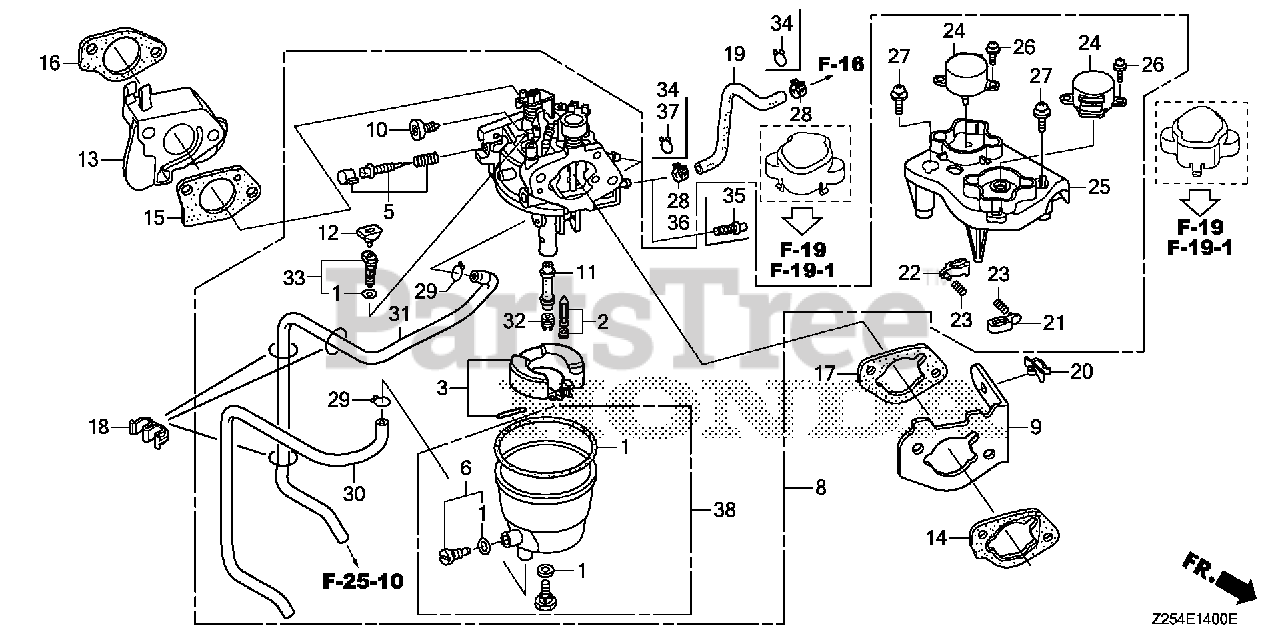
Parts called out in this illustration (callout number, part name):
1	GASKET SET (CARBURETOR NO.)
2	VALVE SET, FLOAT
4	CHAMBER SET, FLOAT
5	SCREW SET, PILOT
6	SCREW SET, DRAIN
7	SCREW SET
8	CARBURETOR ASSY. (BE89G A)
9	HOLDER, TUBE
10	SCREW, STOP
11	NOZZLE, MAIN
12	COLLAR, SETTING
13	INSULATOR, CARBURETOR
14	SPACER, CARBURETOR
15	GASKET, CARBURETOR
16	GASKET, INSULATOR
17	GASKET, AIR CLEANER
18	CLAMP, TUBE (7.5X2)
19	TUBE, FUEL TANK (FKM)
20	CLIP B, HARNESS
21	LEVER, LINK
22	LEVER, LINK
23	SPRING, COMPRESSION COIL
24	MOTOR, THROTTLE CONTROL
25	BRACKET, THROTTLE MOTOR
26	SCREW-WASHER (3X8)
27	SCREW-WASHER (4X12)
28	CLAMP, TUBE (D8)
29	CLIP, TUBE (C8)
30	BULK HOSE, VINYL (4.5X8X1000) (4.5X8X400)
31	BULK HOSE, VINYL (4.5X8X1000) (4.5X8X550)
32	JET, MAIN (#92)
32	JET, MAIN (#95)
32	JET, MAIN (#98)
33	JET SET, PILOT (#40)
38	BOLT KIT, FUEL CHAMBER
